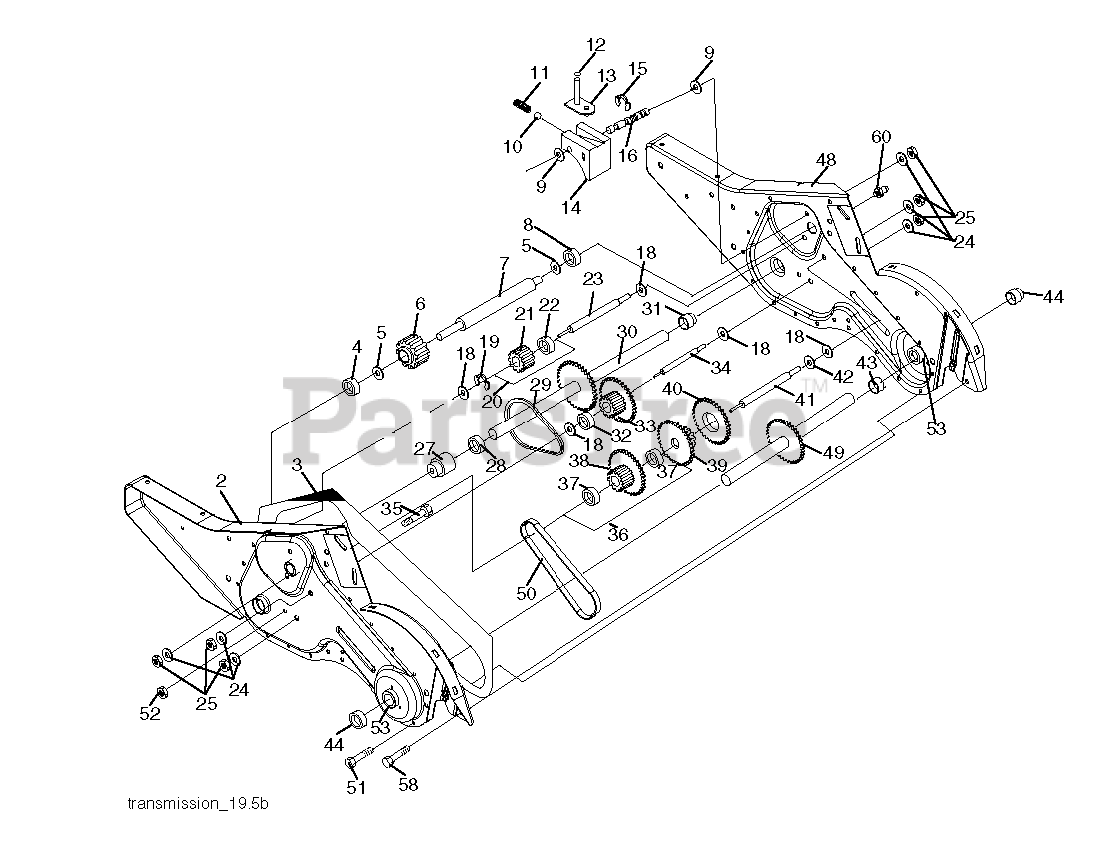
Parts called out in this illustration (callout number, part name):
1	TRANSMISSION ASM.
2	GEARCASE.ASM.CRT.LH.W/BEARING
3	GASKET
4	NEEDLE BRNG LT
5	THRUST WASHER
6	GEAR.PINION.INPUT
7	SHAFT.INPUT."D".TILLER
8	BEARING TI
9	WASHER, SEAL (2 2)
10	STEEL BALL KIT
11	SPRING-SHIFT CRT
13	BRACKET ASM.SHIFT.CRT
14	SHIFT FORK TI
16	SHAFT.SHIFTER.TILLER
20	GEAR ASSY CRT
21	GEAR-REV IDLR CRT
22	NEEDLE BEARING TI
24	LOCKWASHER
25	NUT.ASF.HEX.7/16
27	BEARING, SHAFT LH CRT
30	GROUND SHAFT ASS'Y
31	BEARING, SHAFT RH CRT
33	SPRCKT 8 GEAR CRT
34	SHAFT.SECONDARY.REDUCTION.CRT
35	SCRW WHIZ LOK CRT
36	SPROCKET.ASM.W/BEARING.TILLER
37	BEARING
38	SPROCKET, TINE
41	SHAFT.REDUCTION.TILLER
42	BRNG RACE T
44	SEAL ASM, OIL
48	GEARCASE.ASM.CRT.RH.W/BEARING
49	TINE SHAFT
50	CHAIN.TILLER
51	SCREW
53	KIT.BEARING.TILLER.
58	BOLT SHOULDER 1/4-20 UNC X.875
60	FITTING.GREASE.TAPERED
